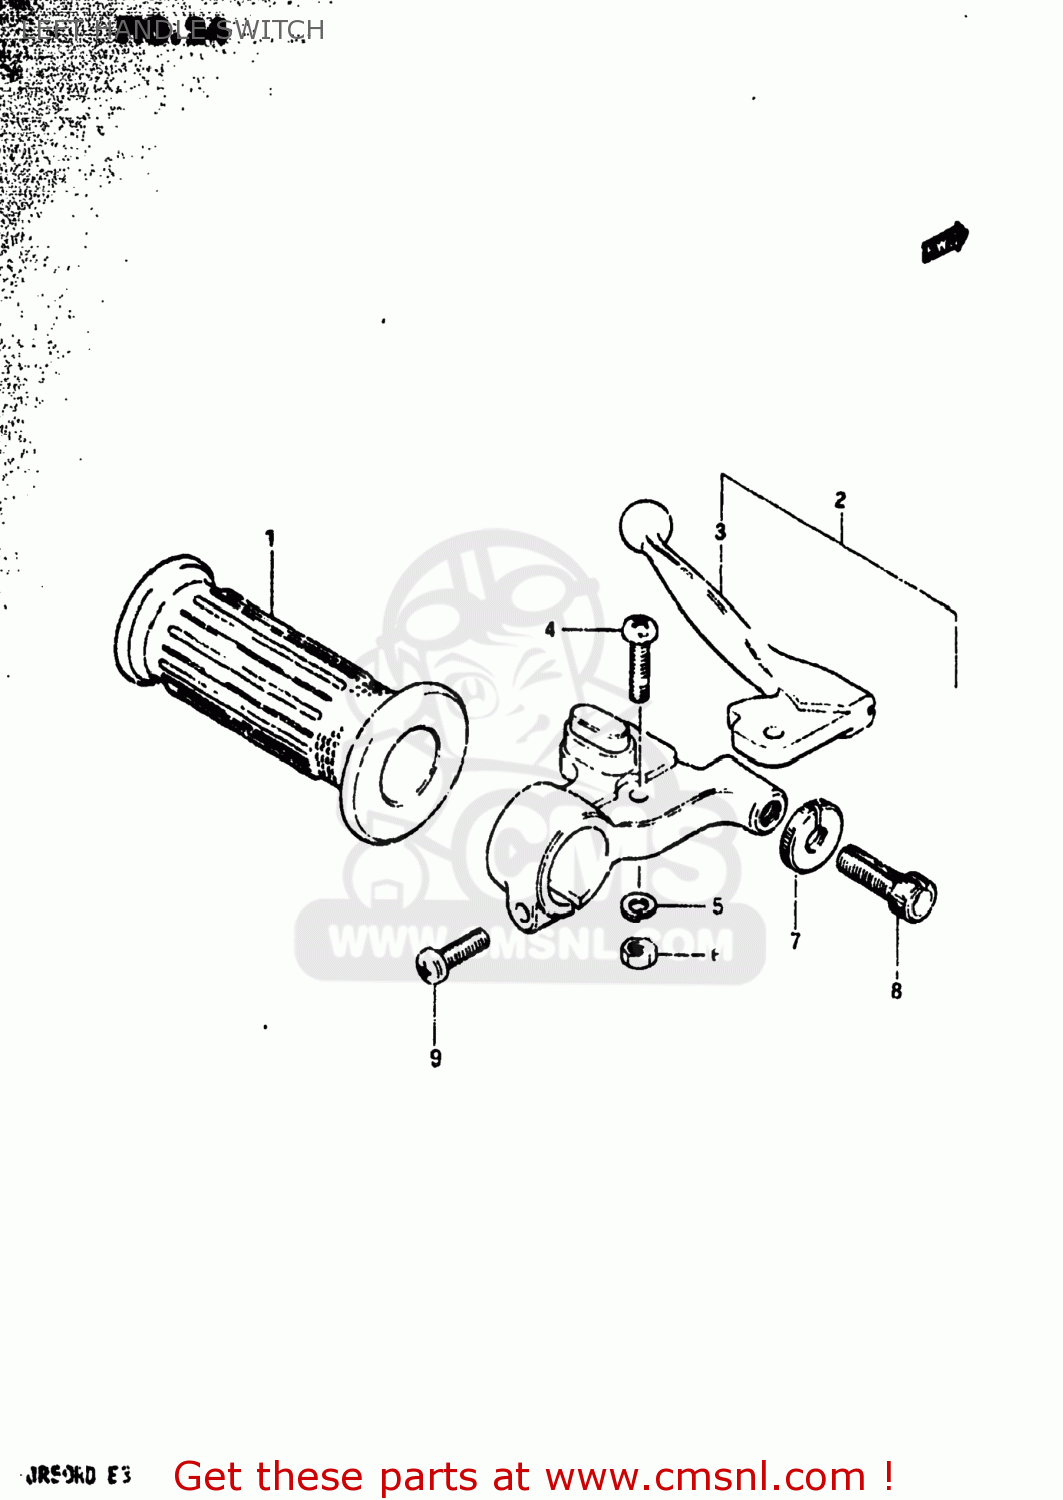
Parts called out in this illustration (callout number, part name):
1	GRIP,L
2	LEVER ASSEMBLY,CLUTCH
3	LEVER,LEFT
4	SCREW
5	LOCK WASHER
6	NUT
7	LOCK NUT
8	BOLT,CABLE ADJUSTER
9	SCREW
